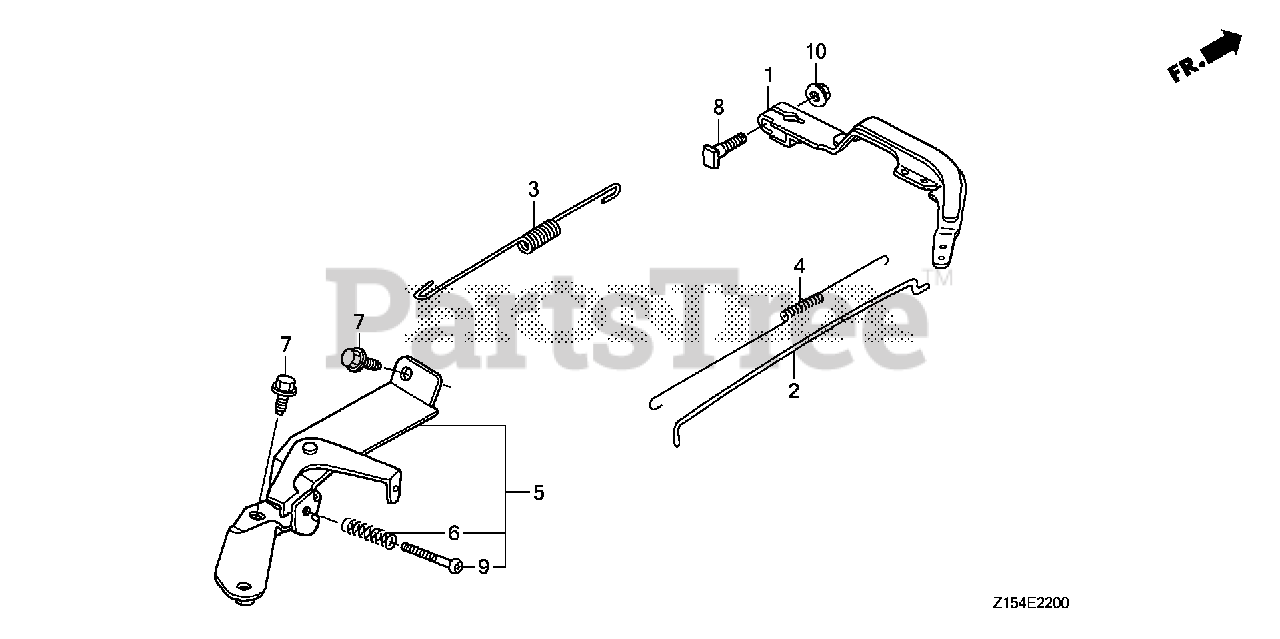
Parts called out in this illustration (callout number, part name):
1	ARM, GOVERNOR
2	ROD, GOVERNOR
3	SPRING, GOVERNOR
4	SPRING, THROTTLE RETURN
8	BOLT, GOVERNOR ARM
10	NUT, FLANGE (6MM)
